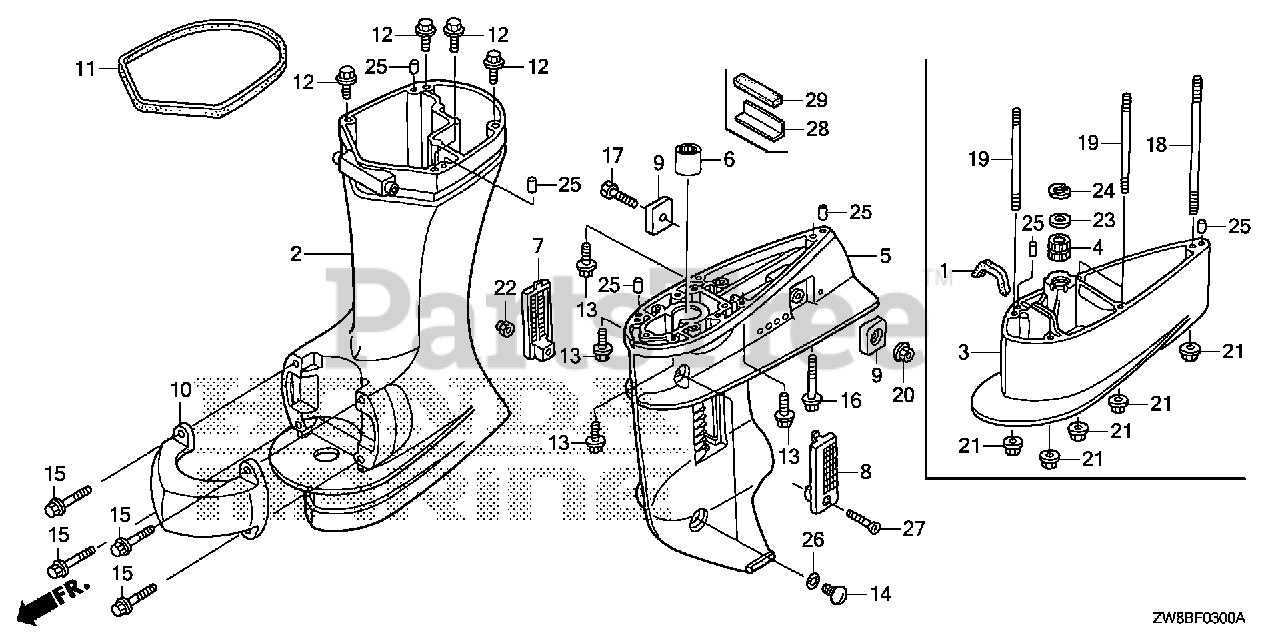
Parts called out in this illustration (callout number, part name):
2	CASE, EXTENSION *NH282MU* (S) (OYSTER SILVER METALLIC-U)
5	CASE, GEAR *NH282MU* (OYSTER SILVER METALLIC-U)
6	BUSH, PINION GEAR
7	SCREEN, R. WATER
8	SCREEN, L. WATER
9	METAL, ANODE
10	HOUSING, MOUNTING (LOWER) *NH282MU* (OYSTER SILVER METALLIC-U)
11	RUBBER, COVER (LOWER)
12	BOLT, FLANGE (8X35) Use from Frame SN 4800713.
13	BOLT, FLANGE (6X23) Use from Frame SN 4800343.
14	BOLT, OIL CHECK
15	BOLT, FLANGE (6X20) (ENGINE NO.)
16	BOLT, FLANGE (6X75)
17	BOLT, HEX. (6X25) Use up to Frame SN 4800342.
20	NUT, SELF-LOCK (6MM)
22	NUT, SELF-LOCK (5MM)
25	PIN, DOWEL (6X10)
26	O-RING (6.9X1.45)
27	SCREW, OVAL (5X28)
28	PLATE, RUBBER SETTING
29	GROMMET, GEAR CASE
